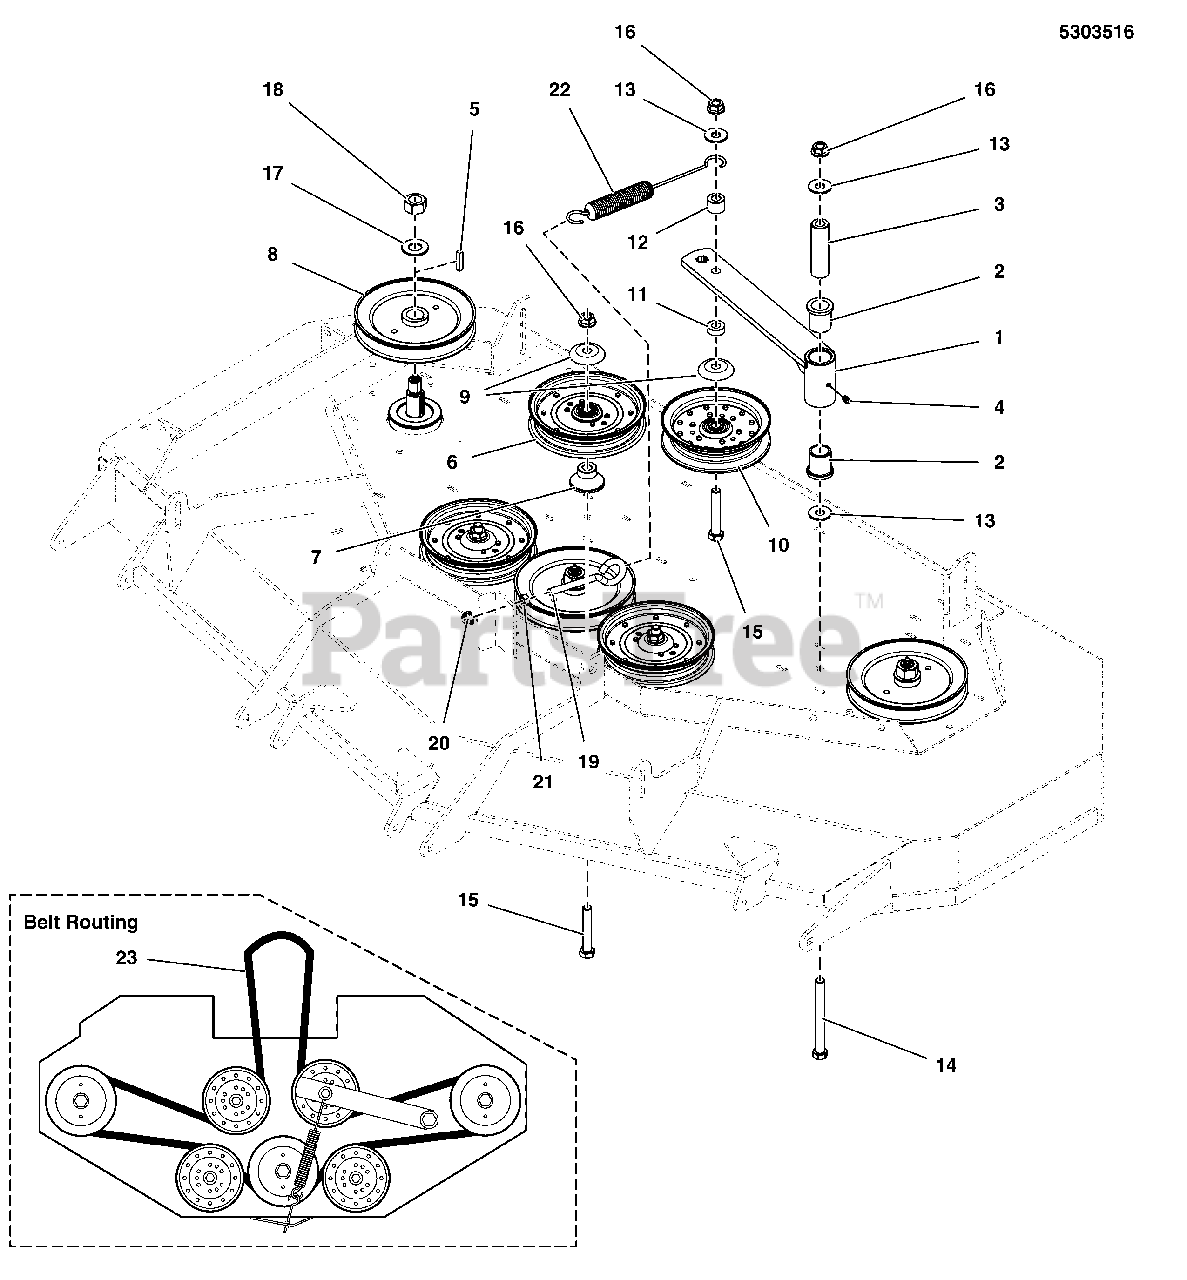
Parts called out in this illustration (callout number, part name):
1	WELD, IDLER ARM (10.50) - BLK
2	BUSHING, FLANGE
3	SPACER, .52 X 1.00 X 3.50
4	GREASE FITTING, 1/4-28 STRAIGHT
5	KEY, 1/4 SQ X 1-1/4
6	PULLEY, FLAT IDLER, 6-3/4"
7	IDLER MOUNT
8	PULLEY, 6.93 EOD X 25MM, SPLIT
9	SHIELD, PULLEY BEARING, CZ
11	SPACER, .52 X 1.00 X .38, CZ
12	SPACER, .52 X 1.00 X .75, CZ
13	WASHER, 1/2 USS
14	BOLT-1/2-13 X 5 GD5 YZ
15	BOLT, 1/2-13 X 3 GD5 YZ
16	NUT, 1/2-13 HEX NYLOCK FLANGE
17	WASHER, 3/4 BELLEVILLE
18	NUT, 3/4-16 HEX
19	EYE BOLT, 3/8-16 X 5, 2.88THRD (5021812)
20	NUT, 3/8-16 HEX NYLOCK FLANGE
21	NUT, 3/8-16 HEX
22	SPRING-EXT, 1.04 ODX10.535LGX.148WR, BLK
23	BELT, 5V-SEC, 178.25"EL, ARAMID, WRAP RC
